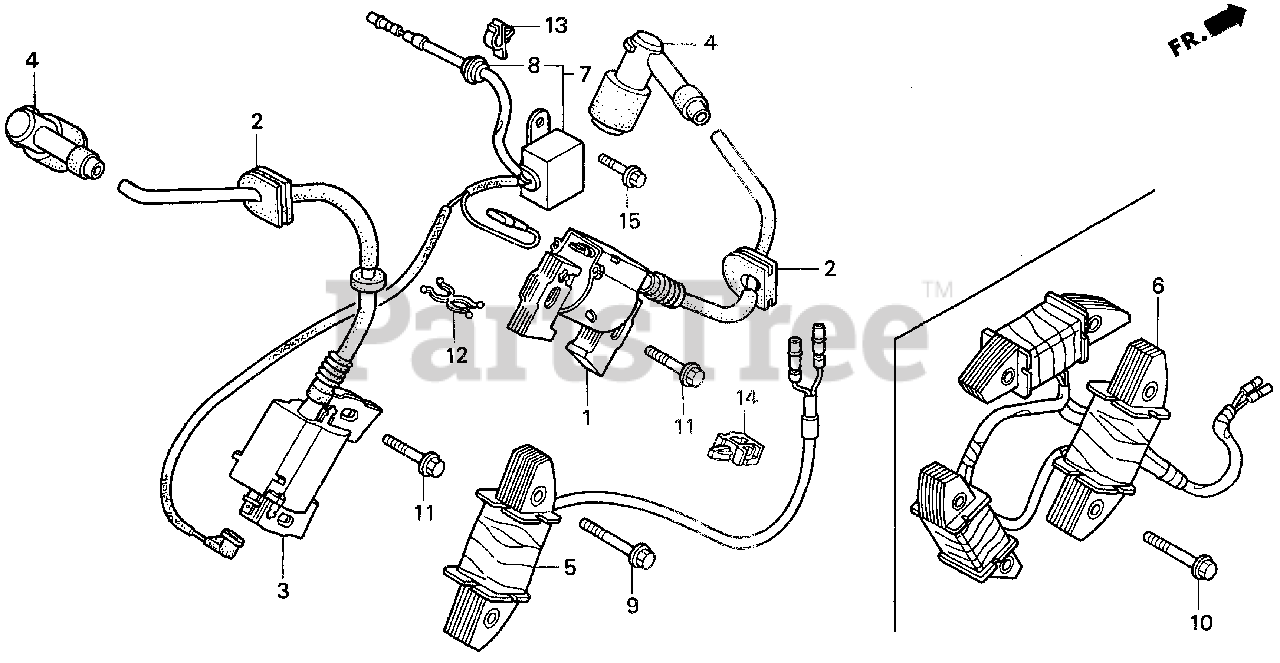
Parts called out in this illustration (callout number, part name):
1	COIL ASSY., R. IGNITION
2	GROMMET, IGNITION WIRE
3	COIL ASSY., L. IGNITION
4	CAP ASSY., NOISE SUPPRESSOR
6	COIL ASSY., CHARGE (12V/20A)
7	DIODE ASSY., ENGINE STOP
8	GROMMET, TOOL
10	BOLT, FLANGE (6X32)
11	BOLT, FLANGE (6X25)
12	CLIP, WIRE HARNESS
15	BOLT, FLANGE (6X8)
